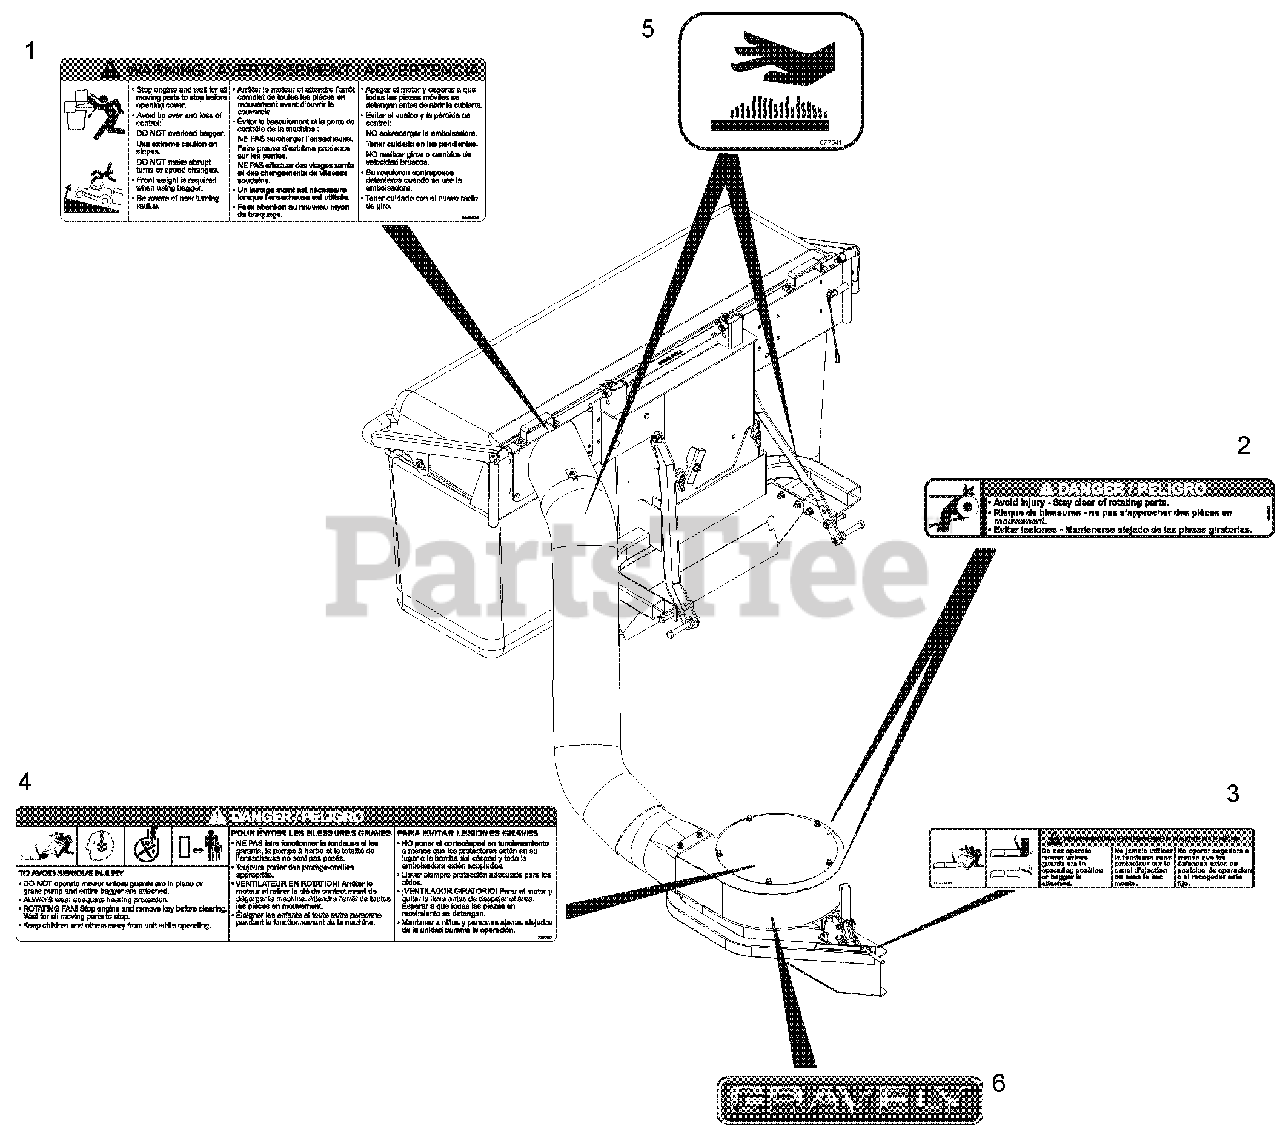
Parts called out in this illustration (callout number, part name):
1	Decal – Warning, Bagger Cover
2	Decal, Danger
3	Decal, Warning
4	Decal – Caution, Grass Pump
5	Decal, Hot Surface
6	Decal, Gravely
